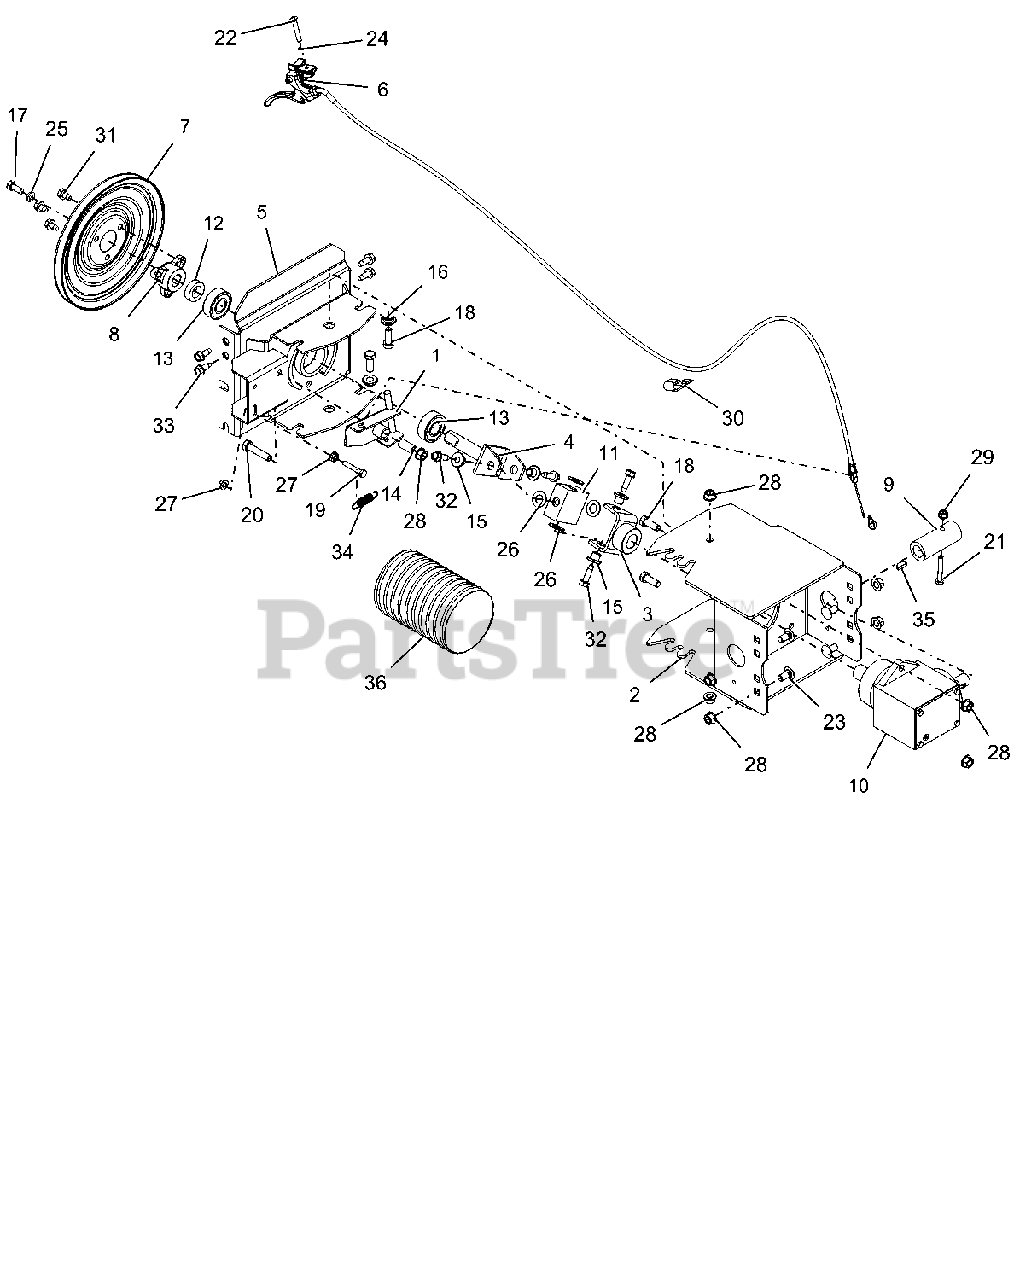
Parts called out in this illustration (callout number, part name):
1	ARM, PIVOT LOCK (BLACK)
2	ADAPTOR, BRUSH FRAME (BLACK)
3	JOINT,UNIVERSAL (BLACK)
4	JOINT, UNIVERSAL (BLACK)
5	ADAPTOR, FRAME -20000 SERIES (BLACK)
6	CABLE, REMOTE BRUSH LOCK
7	PULLEY, SPIN FORM SINGLE GROOVE
8	HUB, ATTACHMENT PULLEY
9	HUB, COUPLING
10	GEARBOX, 1:1 CCW-CW W/CRSBOR
11	BLOCK, UNV
12	SPACER, .755x1.250x.370
13	BRG-BALL .750X1.781X.61
14	BSHG, SLV .385 X .500 X 1.045
15	BSHG, FLG .325X.500X.513X.875
16	BSHG, FLG .406X.88X.270X.140
17	BLT-HEX .31-24X.75 GR5 YWZC
18	BLT-HEX .38-16X1.00 GR5 YWZC
19	BLT-HEX .25-20X1.50 GR5 YWZC
20	BLT-HEX .38-16X1.75 GR5 YWZC
21	BLT-HEX .25-20X1.75 GR5 YWZC
22	SCR, -- MCH .25-20X1.50 OVAL HD
23	BLT-RDHDSQNK .38-16X.75 G5 YWZC
24	WSHR, LK-INT .250 TH TYA
25	WSHR-LK .31X.097 HVY YWZC
26	WSHR-HDND .515X.970X.062
27	@NUT-SPNLK-FLG .25-20 YWZC
28	NUT, LK-TOP-FLG .38-16 YWZC
29	NUT, LK-TOP-FLG .25-20 YWZC
30	CLAMP, J
31	SCR-TAP .31-18X.50 HWH TR YWZ
32	SCR-TAP .31-18X1.00 HWH TR YZ
33	SCR-TAP .31-18X.75 HWH TR YWZ
34	SPRG, EXTENSION
35	KEY, WDRF - .188X.75X.313 REV
36	HOSE, 4" FLEX TUBE PV
